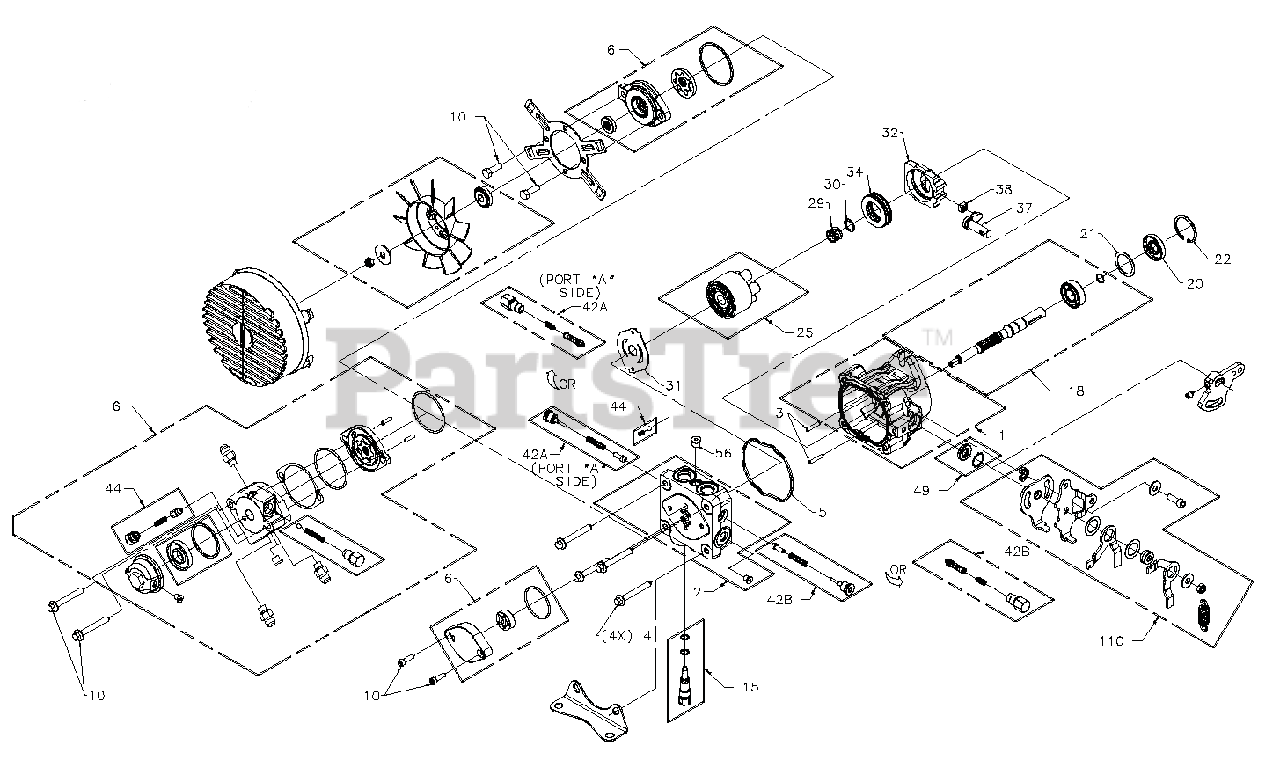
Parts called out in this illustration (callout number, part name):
1	KIT, HSG
2	KIT, ENDCAP STD CHG W/PPT
3	PIN, .219X1
4	HFHCS M8X60
5	Housing O-Ring
6	KIT, CHG PUMP STD CHG, TH
10	HHCS 5/16-18X1
15	KIT, BYPASS VALVE
18	KIT, PUMP SHAFT
20	SEAL, LIP 17X40X7
21	WASHER 1.23X1.56X.04
22	RING, RET 1.56 INT
25	KIT, 10 CC BLOCK
29	SPRING. BLOCK
30	WASHER. THRUST .59 X .79 X .04
31	PLATE, VALVE
32	SWASHPLATE. VARIABLE
34	BEARING. THRUST 30 X 52 X 13
37	ARM. TRUNNION TAPERED SQUARE
38	GUIDE. SLOT
42	KIT, SHOCK VALVE 200 BAR
44	KIT, CHG RELIEF
49	KIT, PUMP SEAL
56	PLUG 7/16-20 (METAL)
110	RETURN KIT
NS	KIT, PUMP SEAL
